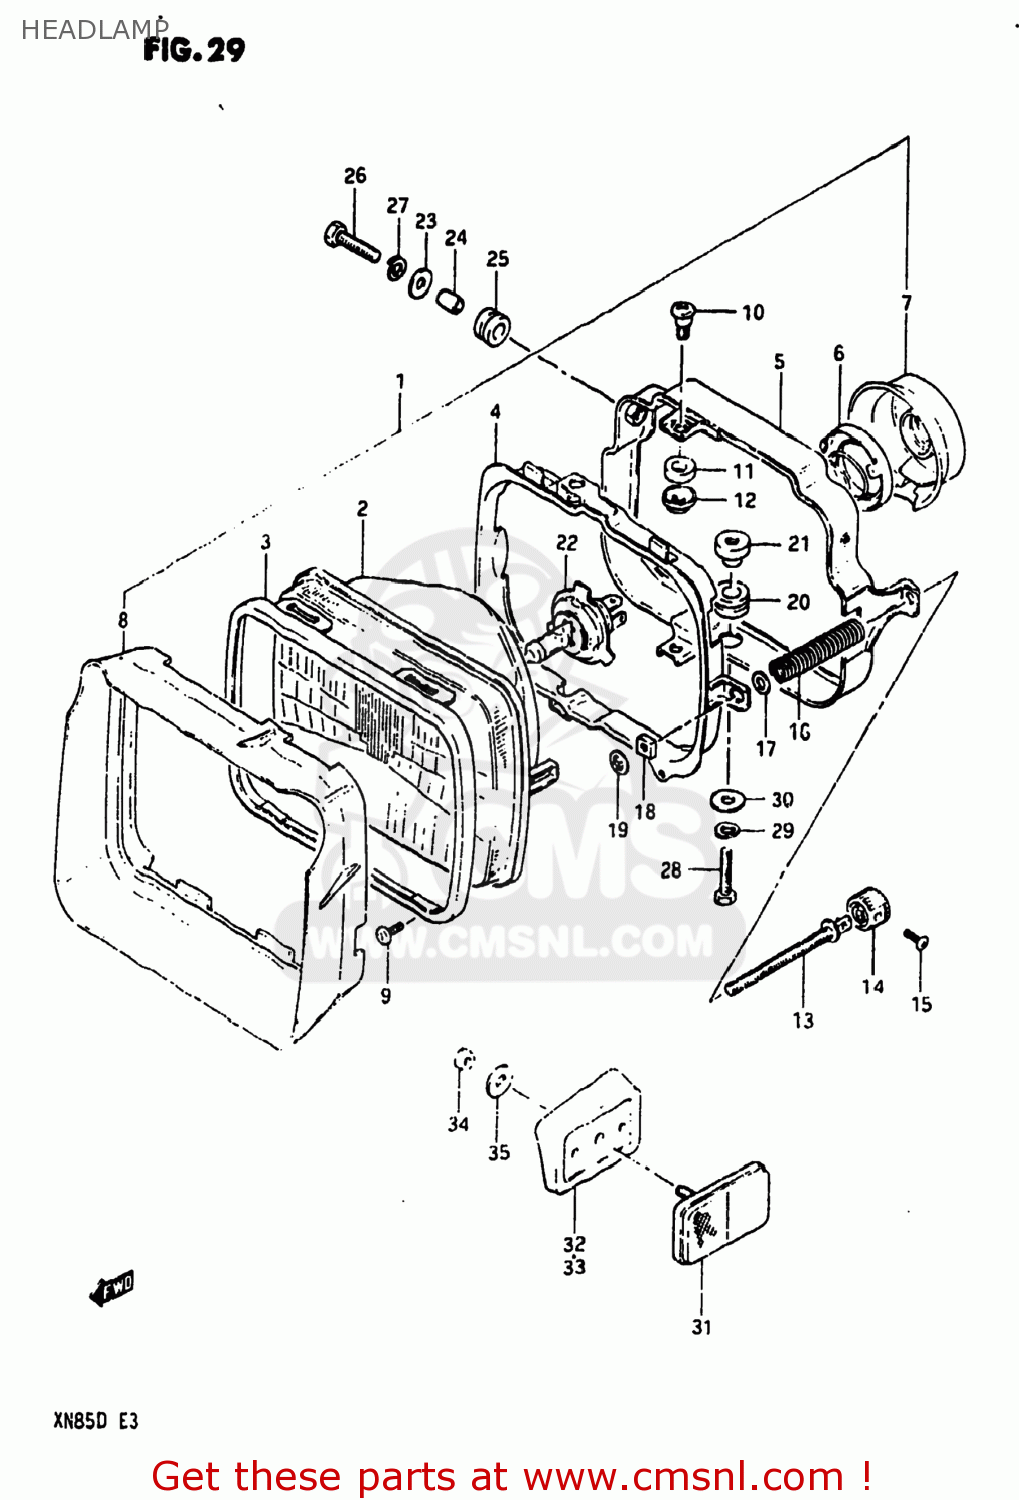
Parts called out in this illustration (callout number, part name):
1	HEADLAMP ASSEMBLY
2	LAMP UNIT
3	RETAINER
4	RING,MOUNTING
5	HOUSING
6	HOLDER
7	COVER,HEADLAMP SOCKET
8	SHADE,HEADLAMP UNIT
9	SCREW
10	SCREW
11	SPACER
12	NUT,ADJUSTING
13	SCREW,ADJUSTING
14	KNOB,ADJUSTER
15	SCREW
16	SPRING
17	WASHER
18	NUT
19	NUT,HEADLAMP ADJUSTER
20	CUSHION
21	NUT
22	BULB(12V60/55W,H4)
23	WASHER
24	SPACER (6.1X8X9.5)
25	CUSHION
26	BOLT
27	LOCK WASHER
28	SCREW(6X20)
29	LOCK WASHER
30	WASHER 6MM
31	REFLECTOR,REFLEX
32	SPACER,FRONT SIDE REFLECTOR
33	SPACER,FRONT SIDE REFLECTOR
34	NUT
35	WASHER(5.2X16X1)
